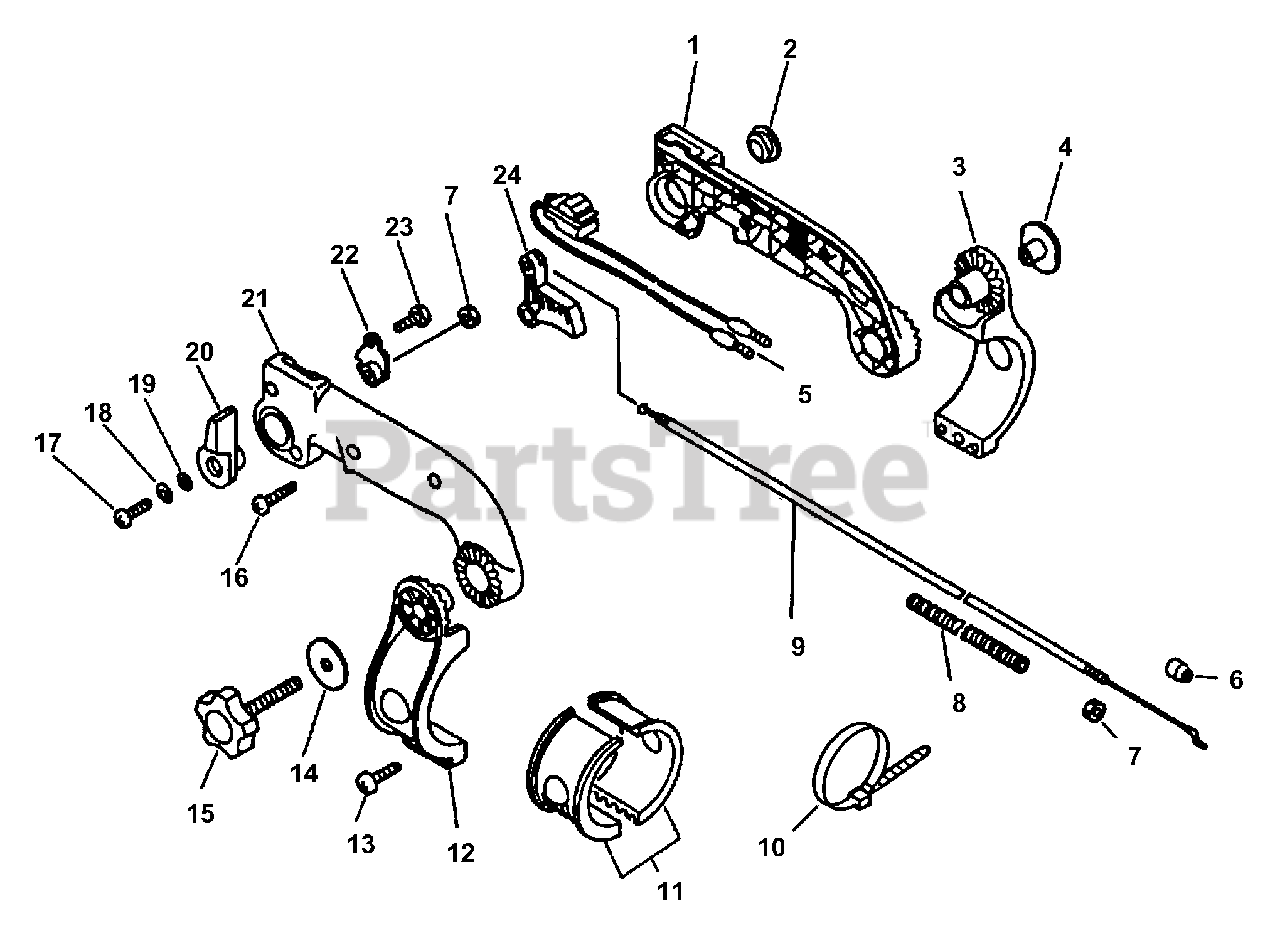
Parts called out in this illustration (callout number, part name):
1	HANDLE, CONTROL - RIGHT
3	BRACKET, HANDLE - RIGHT
5	IGNITION SWITCH ASSY
6	CAP, DUST
7	LOCKNUT - 6
8	TUBE, PROTECTIVE - CORRUGATED
9	CABLE, THROTTLE
10	TIE, CABLE - LARGE
12	BRACKET, HANDLE - LEFT
13	SCREW - 5X20 -- TAPPING
14	WASHER - 6
15	THUMBSCREW
16	SCREW - 4X22
17	SCREW - 6X20
18	LOCKWASHER - 6
19	WASHER - 6
20	CONTROL, THROTTLE
21	HANDLE, CONTROL - LEFT
22	BRACKET, THROTTLE
23	SCREW - 4X10
24	TRIGGER, THROTTLE
